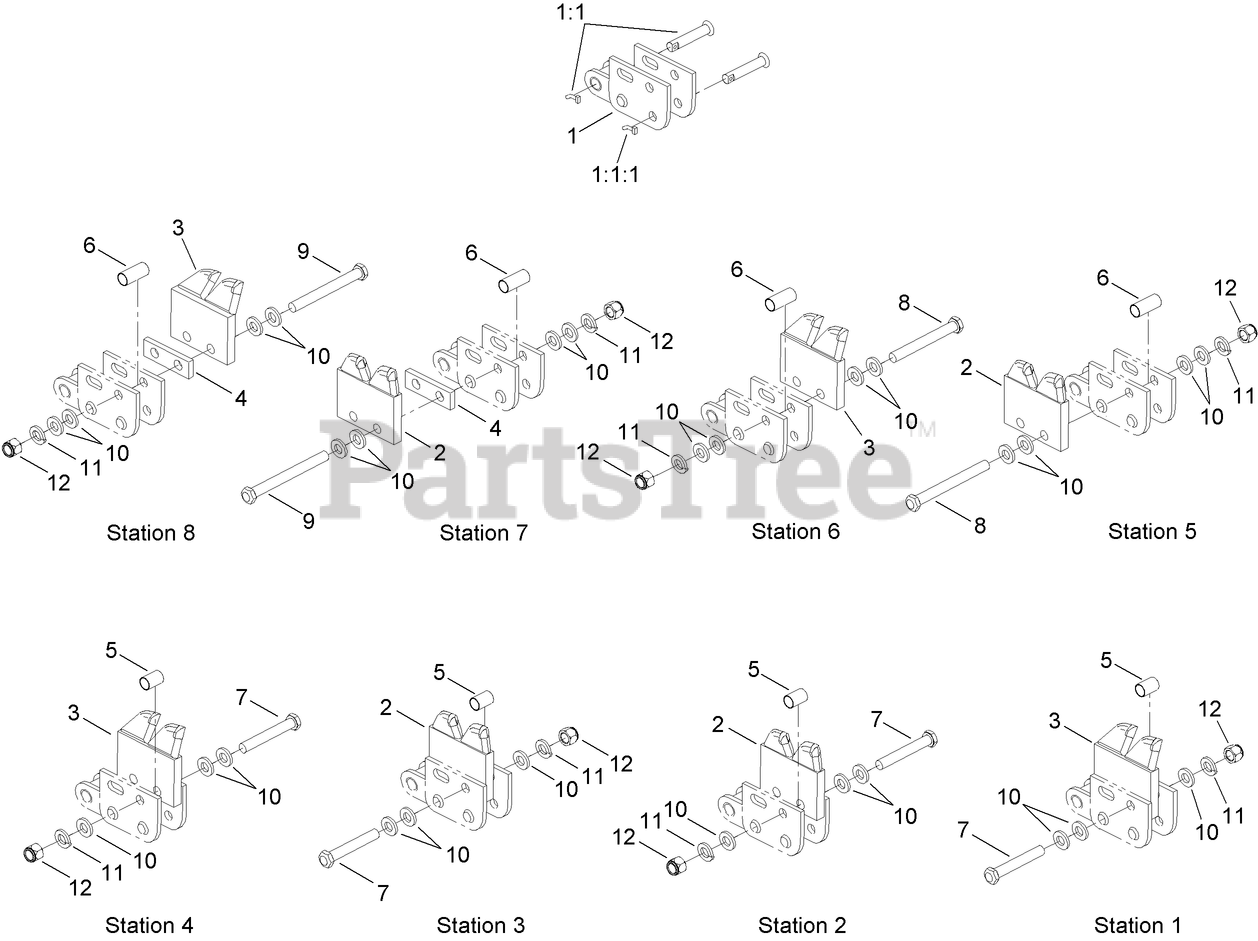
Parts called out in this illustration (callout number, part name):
1	CHAIN REPAIR LINK ASM
1:1	NOTCHED PIN AND KEEPER ASM
1:1:1	PIN-KEEPER
2	TOOTH-TERMINATOR, RH
3	TOOTH-TERMINATOR, LH
4	SPACER-FLAT
5	SPACER-TUBE, INSIDE ADAPTER
6	SPACER-TUBE, OUTSIDE MOUNT
7	BOLT-HH
8	BOLT-HH
9	BOLT-HH
10	WASHER-FLAT
11	WASHER-LOCK
12	NUT-LOCK
